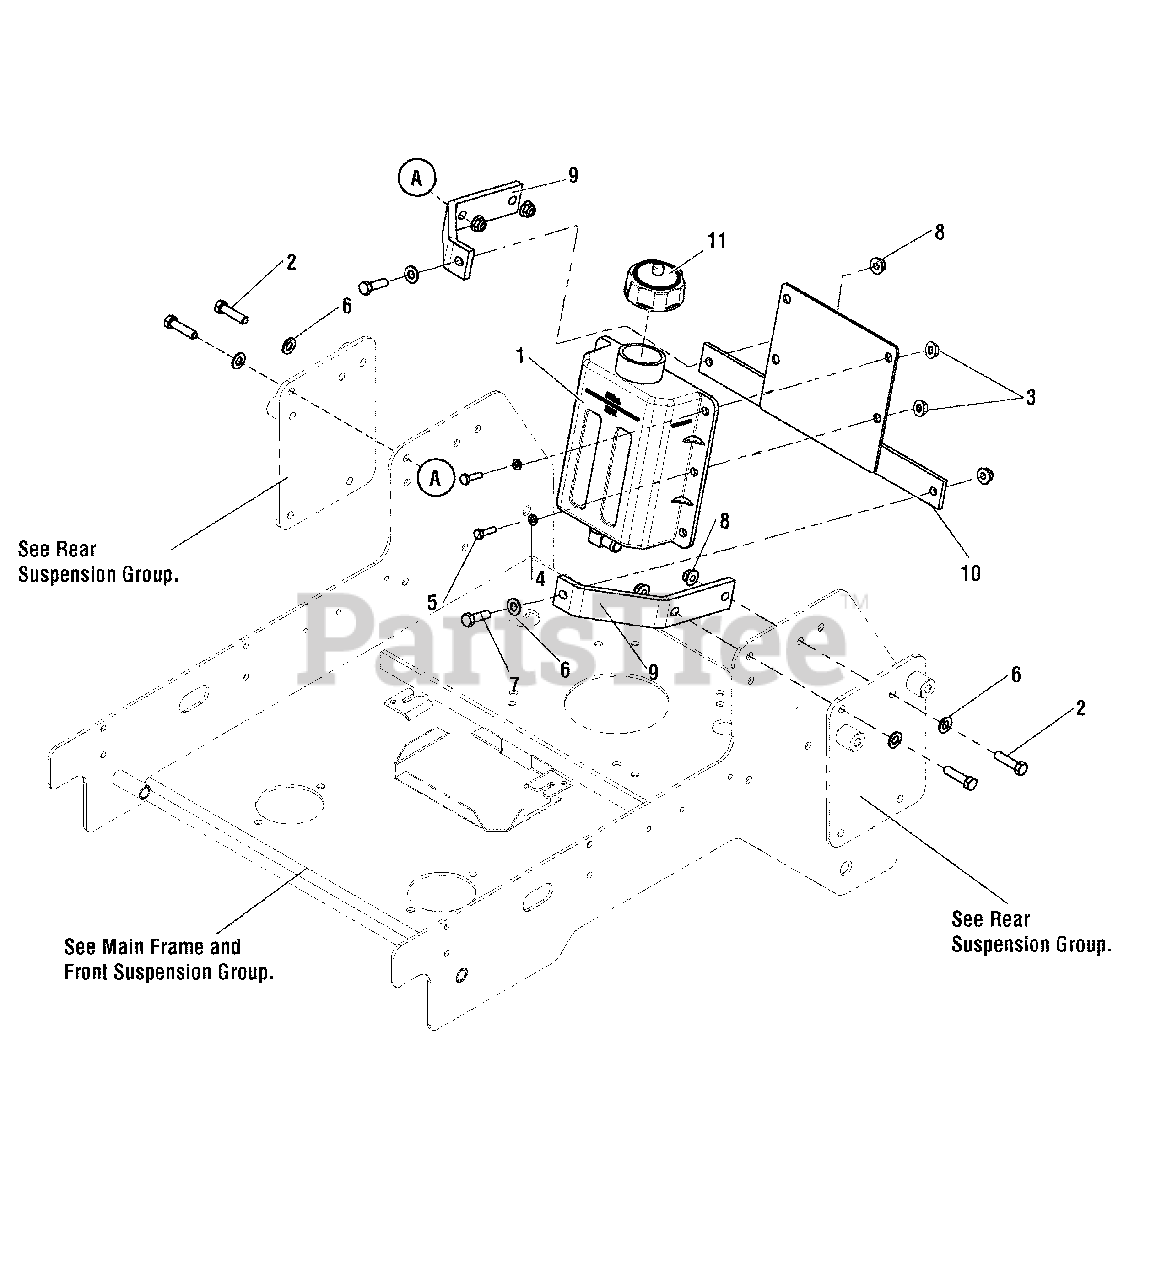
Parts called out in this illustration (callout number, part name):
1	TANK, HYDRAULIC, ASSEMBLY
2	BOLT, 3/8-16 X 1-1/2" GD5 YZ
3	NUT, 1/4-20 HEX NYLOCK FLANGE (5025391)
4	WASHER, 1/4 SAE (5025154)
5	BOLT, 1/4-20 X 1", GD
6	WASHER 3/8" SAE
7	BOLT, 3/8-16 X 1-1/4" GD5
8	NUT, 3/8-16 HEX NYLOCK FLANGE
9	BRACKET, HYDRAULIC TANK - ORANGE
10	WELD, HYD TANK MOUNT - ORANGE
11	CAP, HYDRAULIC
